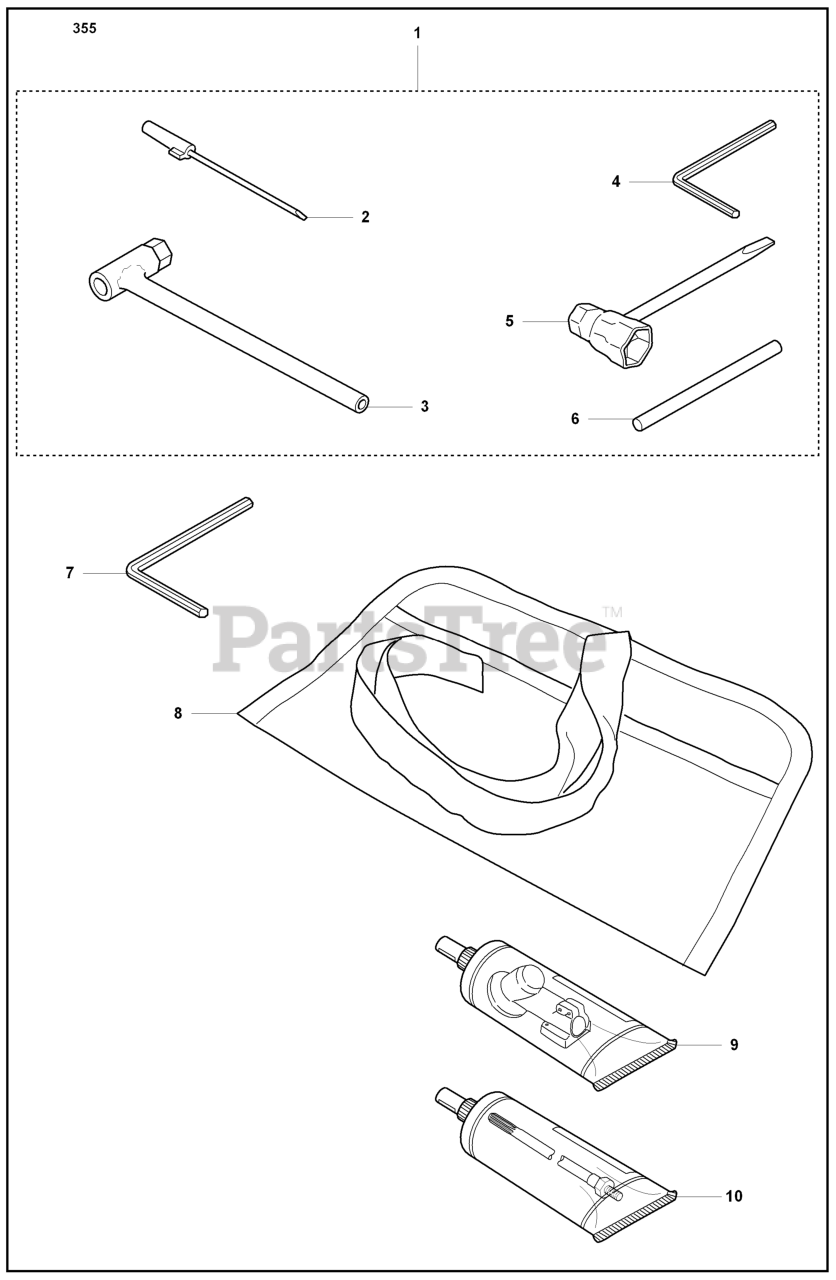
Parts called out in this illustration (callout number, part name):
1	RP ACCESSORY BAG
1	ACCESORY BAG
2	SCREWDRIVER
4	L-KEY WRENCH
5	COMBI TOOL
6	LOCKING PIN
7	KEY
9	BEVEL GEAR GREASE
10	DRIVE SHAFT GREASE (200 G)
